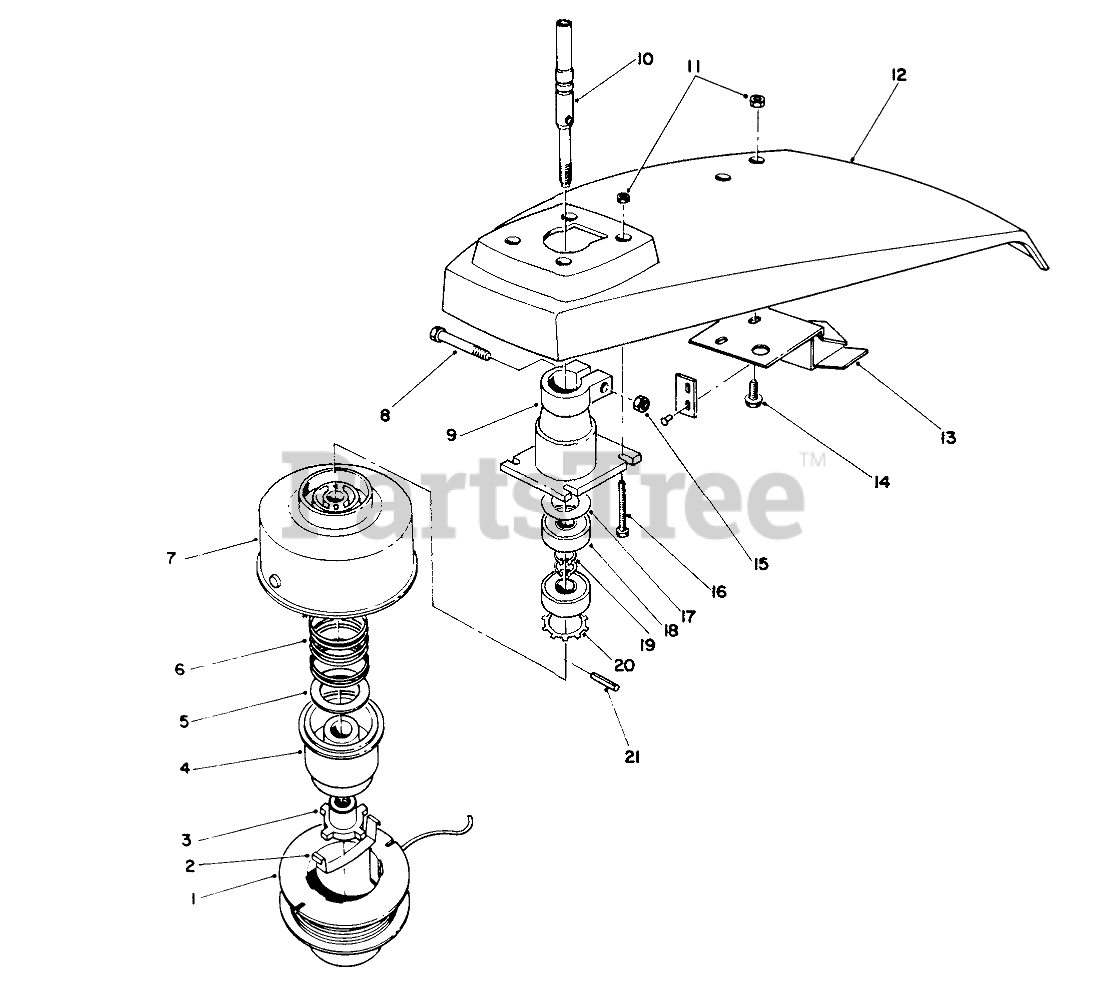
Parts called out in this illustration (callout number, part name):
1	Empty Spool
2	SADDLE-SPOOL CAP
3	DRIVER
4	SPOOL CORE
5	WASHER-FLAT
6	SPRING COMPRESSION
7	DRUM/EYELET
8	SCREW-HH
9	Housing-Bearing (Incl. Ref. #10, 17-21)
10	Shaft-Power
11	NUT-LOCK, NI
12	GRASS SHIELD-PLASTIC
13	BRKT/KNIFE BLD ASM
14	SCREW-HWH
15	NUT-LOCK, NI
16	SCREW-HH
17	FLAT WASHER
18	BEARING-BALL
19	RING-SNAP
20	SPRING GRIP
21	COIL PIN
